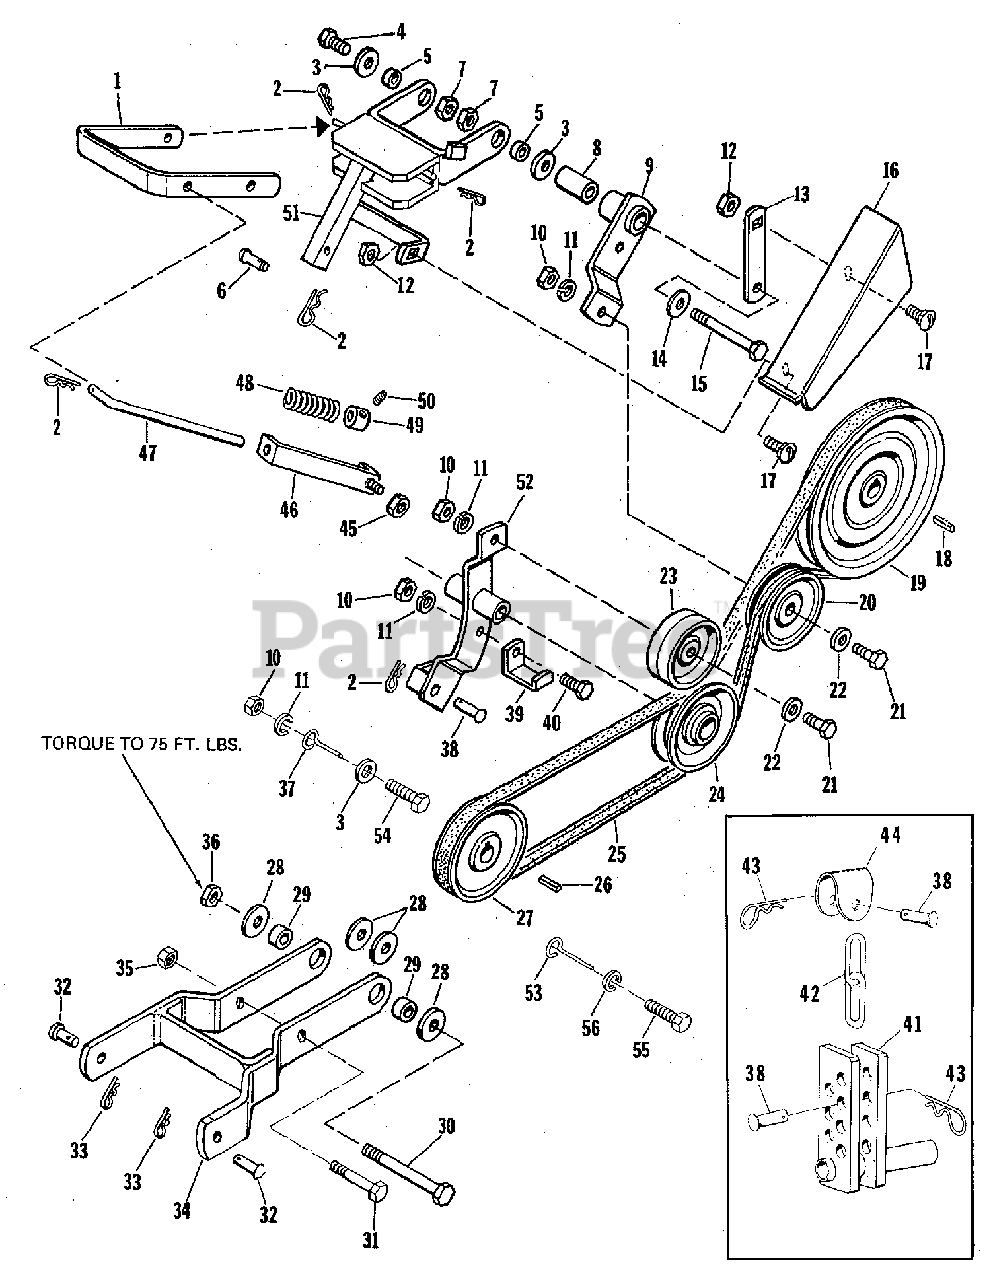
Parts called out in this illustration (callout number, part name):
1	BLADE ASSEMBLY, R.H.
2	TINE, Blade, L.H.
3	SCREW, Hex Cap, 7/16-20 x 2
5	TINE BLADE, R.H.
6	NUT, Hex Lock, 7/16-20
8	PIN, Cotter, 1/8 x 3/4
11	BLADE ASSEMBLY, Inner (R.H.)
12	TINE, Blade, L.H.
13	SCREW, Hex Cap, 7/16-20 x 2
15	TINE, Blade, R.H.
16	NUT, Hex Lock, 7/16-20
17	HUB, Attachment
18	KEY, Woodruff, 3/16-3/4
19	BLADE ASSEMBLY, Inner (L.H.)
20	TINE, Blade, L.H.
21	SCREW, Hex Cap, 7/16-20 x 2
23	TINE, Blade, R.H.
24	NUT, Hex Lock, 7/16-20
25	HUB, Attachment
26	BLADE ASSEMBLY, L.H.
27	TINE, Blade L.H.
28	TINE, Blade R.H.
30	SCREW, Hex Cap, 7/16-20 x 2
31	NUT, Hex Lock
33	PLATE, End, Deflector, R.H.
34	BOLT, Carriage, 5/16-18 x 1/2
35	WASHER, Lock, 5/16"
36	NUT, Hex, 5/16-18
37	DEFLECTOR, R.H.
38	SCREW, Hex Cap, 3/8-16 x 1
39	WASHER, Lock, 3/8
40	SCREW, Hex Cap, 3/8-16 x 5/8
41	SCREW, Hex Cap, 3/8-16 x 7/8
42	BOLT, Carriage, 5/16-18 x 3/4
44	CHANNEL, Reinforced
45	NUT, Hex, 3/8-16
46	PLATE, End, Defletor, L.H.
47	DELFECTOR, L.H.
